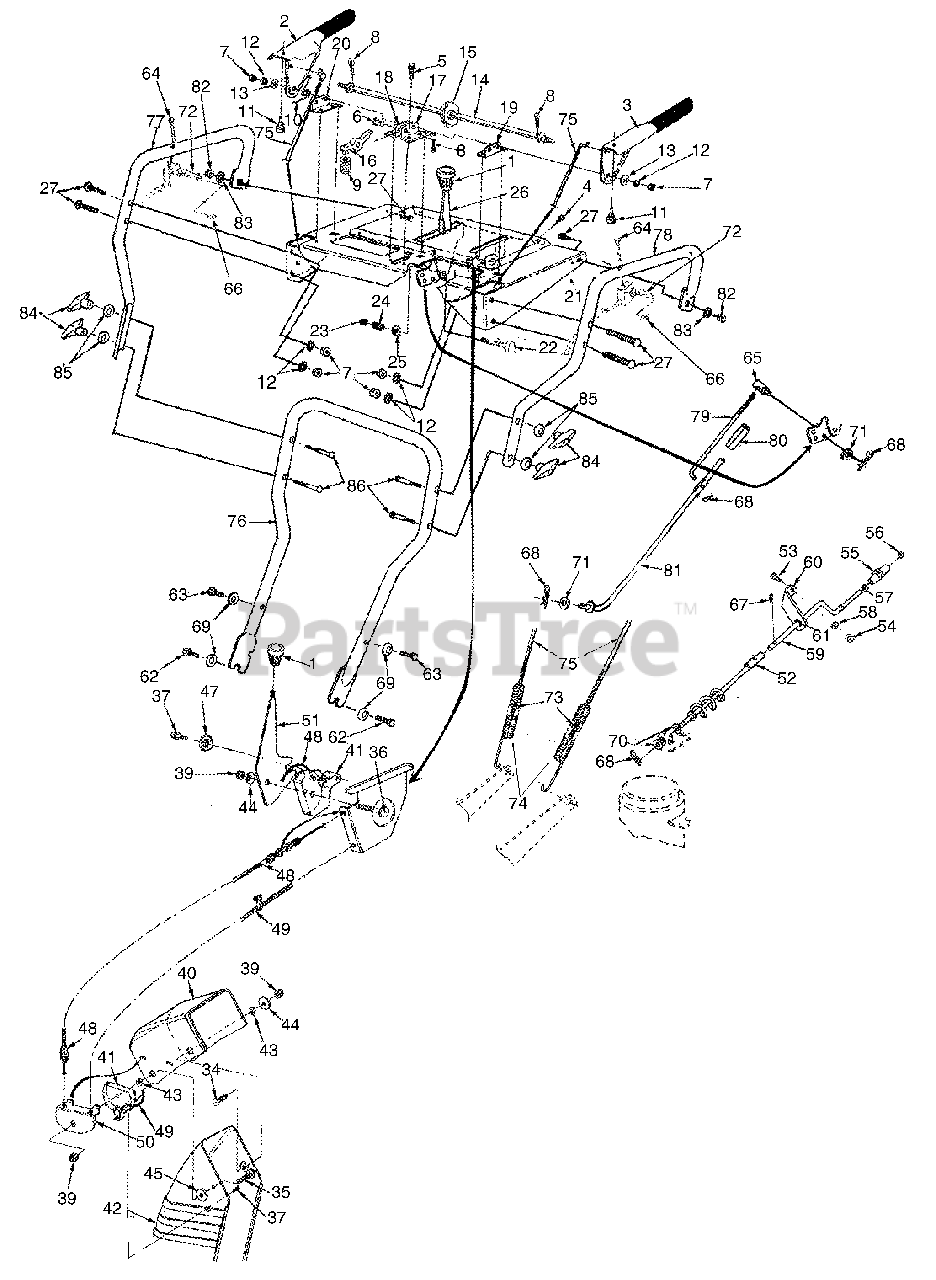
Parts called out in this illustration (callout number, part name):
1	Sml Shift Knob 1.6 Dia Sentar
2	Engage Handle Le Blk Dip Rh
3	Engage Handle Lf Blk Dip Lh
4	Pan Head B-tapp Scr #10 x .5
5	Hwhd Sf-tap Scr 1/4-20 x 1/2 Lg.
6	Clevis Pin .31 Dia x 1.0
7	Nut Hex 5/16-18 Gd 5
8	Cot-pin 3/32 Dia x 1.0
9	Comp Spring .36 Dia x 1.0 Lg
10	Spring Torsion .44 ID
11	Rubber Bumper .63 Dia
12	Lock Washer 5/16
13	Wsher Spcl. .345 Sq. x .72 OD
15	Clutch Lock Cam
16	Clutch Lock Pawl
22	Scr Hex Cap 3/8-24 x 1.5 Gd 5
23	Hex Ins L-nut 3/8-24
24	Compression Spring .39 ID x .88
25	Bell Wash .40 ID x .88 OD x .06
34	Carriage Bolt 5/16-18 x 1.00
35	Carriage Bolt 5/16-18 x 1.75
36	Hex Scr 5/16-18 x 1.5
37	HWHD B Tapp Scr 1/4 x 5/8 Zn
39	Hex Ins L-nut 5/16-18
40	6" Upper Chute Remote Tilt
41	Chute Tilt Cable Guide
42	6" Lower Chute Remote Tilt
43	Chute Pivot Spacer
44	Fl-wash .344 ID x .88 OD x .063
45	Flt Wshr .344 x 1.125 x .125
47	Contoured Washer
48	Chute Control Cable 66"
49	Chute Control Cable 66" W/clip
54	Hex Nut 1/4-20
55	Chute Crank Knob Countersink
56	Push Cap 3/8 Palnut #375011
57	Flat Washer .38 ID x .60 OD x .033
58	Bell Wash .26 ID x .75 OD x .06T
61	Plastic Bushing .380 ID
62	Hex Scr 3/8-16 x .75
63	Hex Scr 3/8-16 x 1.75
64	Scr Oval C/sunk #10-24 x 1.75
65	Adjustment Ferrule
66	#10-24 Flat Weld Nut
67	Internal Cot-pin 1/2 Dia
68	Inter Cot-pin 5/16 Dia
69	Bell Wash .4 ID x .88 OD x .06
70	Fl-wash .406 ID x .74 OD x .063
71	Fl-wash Sae .34 x .68 x .062
72	Trigger Ass'y Steer
73	Hex Ins L-nut 1/4-20
74	Extension Spring
75	Cable Clutch Drive
76	Handle Lower
79	Upper Shift Rod 5/16 x 10.57
80	2 Pc Shift Rod Connector
81	Lower Shift Rod 3/8 x 14.75
82	Hex Nut 1/4 - 20
83	Bell Wash .26 ID x .75 OD x .06T
85	Bell Wash .345 ID x .88 OD x .060
86	Carriage Bolt 5/16 -18 x 2.5
